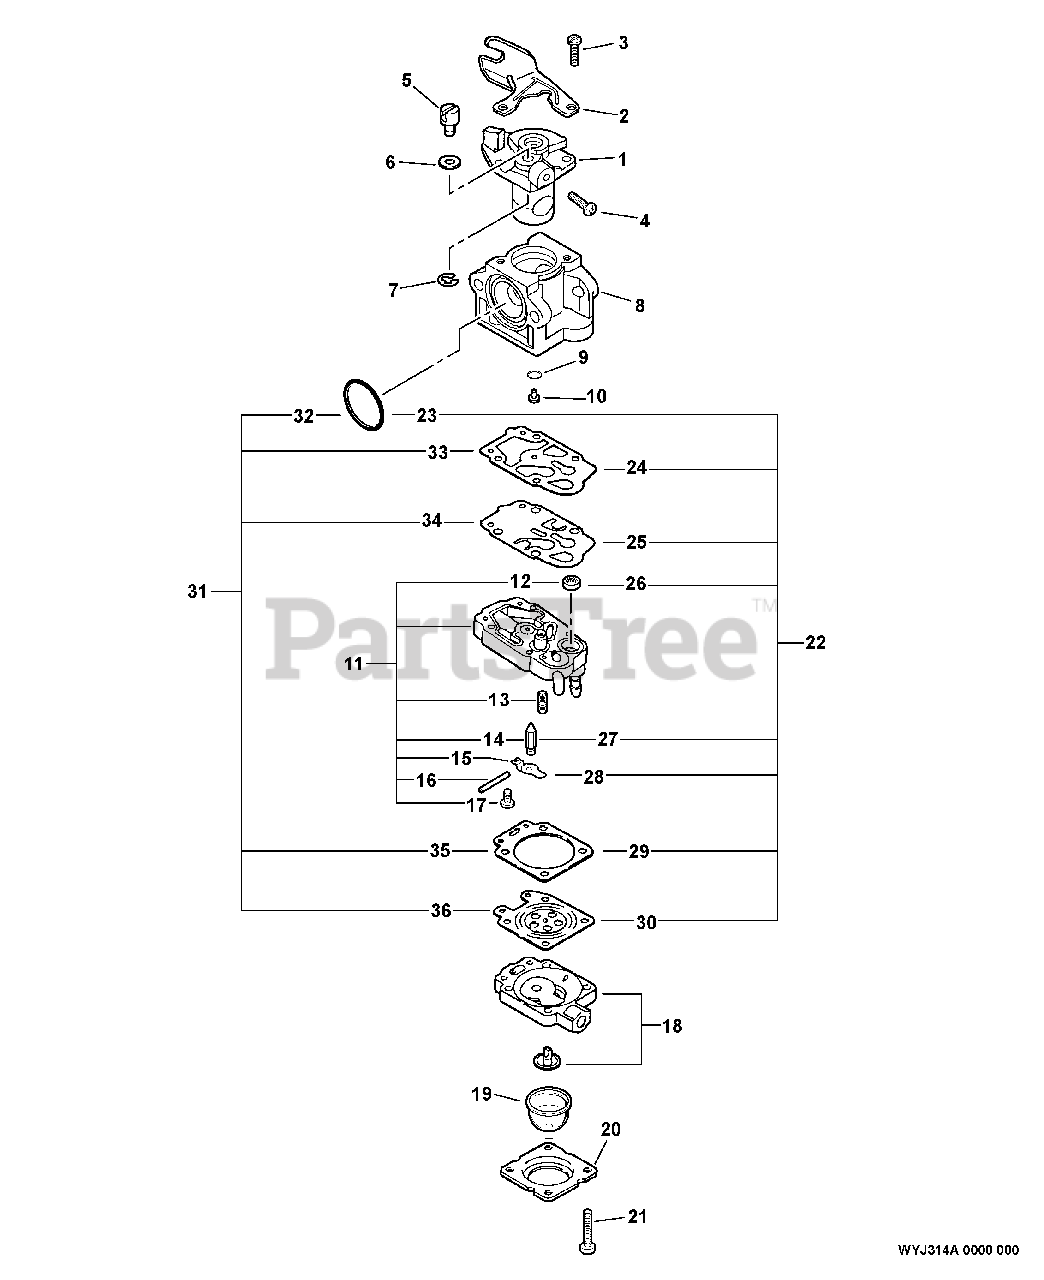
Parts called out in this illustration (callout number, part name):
1	THROTTLE VALVE ASSY
2	BRACKET, THROTTLE CABLE
8	BODY, CARBURETOR
10	JET, MAIN #34
11	PUMP BODY ASSY
12	STRAINER
13	SPRING, METERING LEVER
14	VALVE, INLET NEEDLE
15	LEVER, METERING
16	PIN, METERING LEVER
18	BODY ASSY, PURGE
19	BULB, PURGE
20	RETAINER, PURGE BULB
22	REPAIR KIT, CARBURETOR
23	SEAL
24	GASKET, PUMP
25	DIAPHRAGM, PUMP
26	STRAINER
27	VALVE, INLET NEEDLE
28	LEVER, METERING
29	GASKET, DIAPHRAGM
30	DIAPHRAGM, METERING
31	GASKET / DIAPHRAGM KIT
32	SEAL
33	GASKET, PUMP
34	DIAPHRAGM, PUMP
35	GASKET, DIAPHRAGM
36	DIAPHRAGM, METERING
